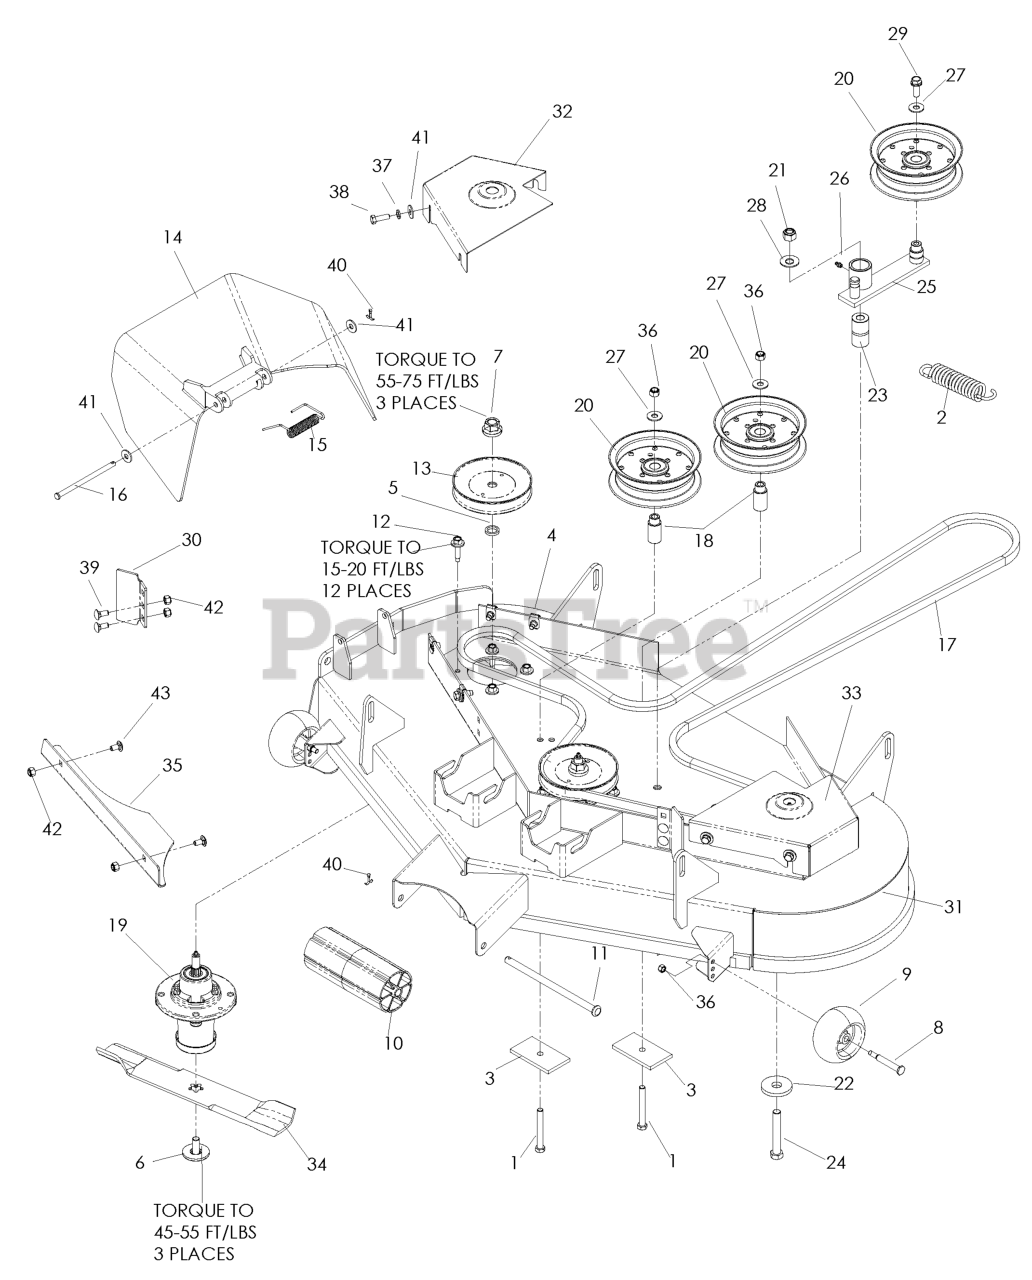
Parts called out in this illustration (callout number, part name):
1	HCS 3/8C X 3
3	SUPPORT PLATE
4	U-CLIP 5/16-18 NUT RETAINER
5	WASHER-SPACER
6	BLADE BOLT ASSY-7/16" TB REPL
7	LOCKNUT - 9/16
8	SHOULDER BOLT 1/2X2-5/8 ZD SPE
9	GAUGE WHEEL
10	NOSE ROLLER 48"
11	NOSE ROLLER ROD
12	WASHER HEAD SCREW
13	PULLEY MANDREL
14	DISCHARGE CHUTE 48"
15	SPRING - TORSION
16	PIN-CLEVIS 5/16 DIA X 5.19 ZD
17	DECK BELT
18	IDLER BUSHING
19	MANDREL.DECK.ASSEMBLY
20	PULLEY, IDLER
21	NUT 1/2-13 HEX NYLOC ZD
22	WASHER, SUPPORT
23	PIVOT BUSHING
24	HCS 1/2C X 3 1/4
26	ZERK
27	WASHER 3/8 FLAT
28	WASHER 1/2 FLAT
29	4CS 3/8C X 1 SERRATED HEAD
31	DECK W/DECALS 48"
32	BELT SHIELD W/DECALS 48 RT
33	BELT SHIELD W/DECALS 48 LT
34	BLADE, 16-1/4"
35	CONFINEMENT PLATE 48" BLK
36	NUT 3/8-16 NYLOC
37	WASHER.LOCK.HVY.HLCL.SPR.5/16
38	HCS 5/16C X 1
39	BOLT 5/16C X 3/4" CARRIAGE
40	RP_COTTER PIN 1/8 X 3/4
41	WASHER 5/16 FLAT
42	NUT 5/16 NYLOC
43	CARRIAGE BOLT 5/16C X 5/8"
